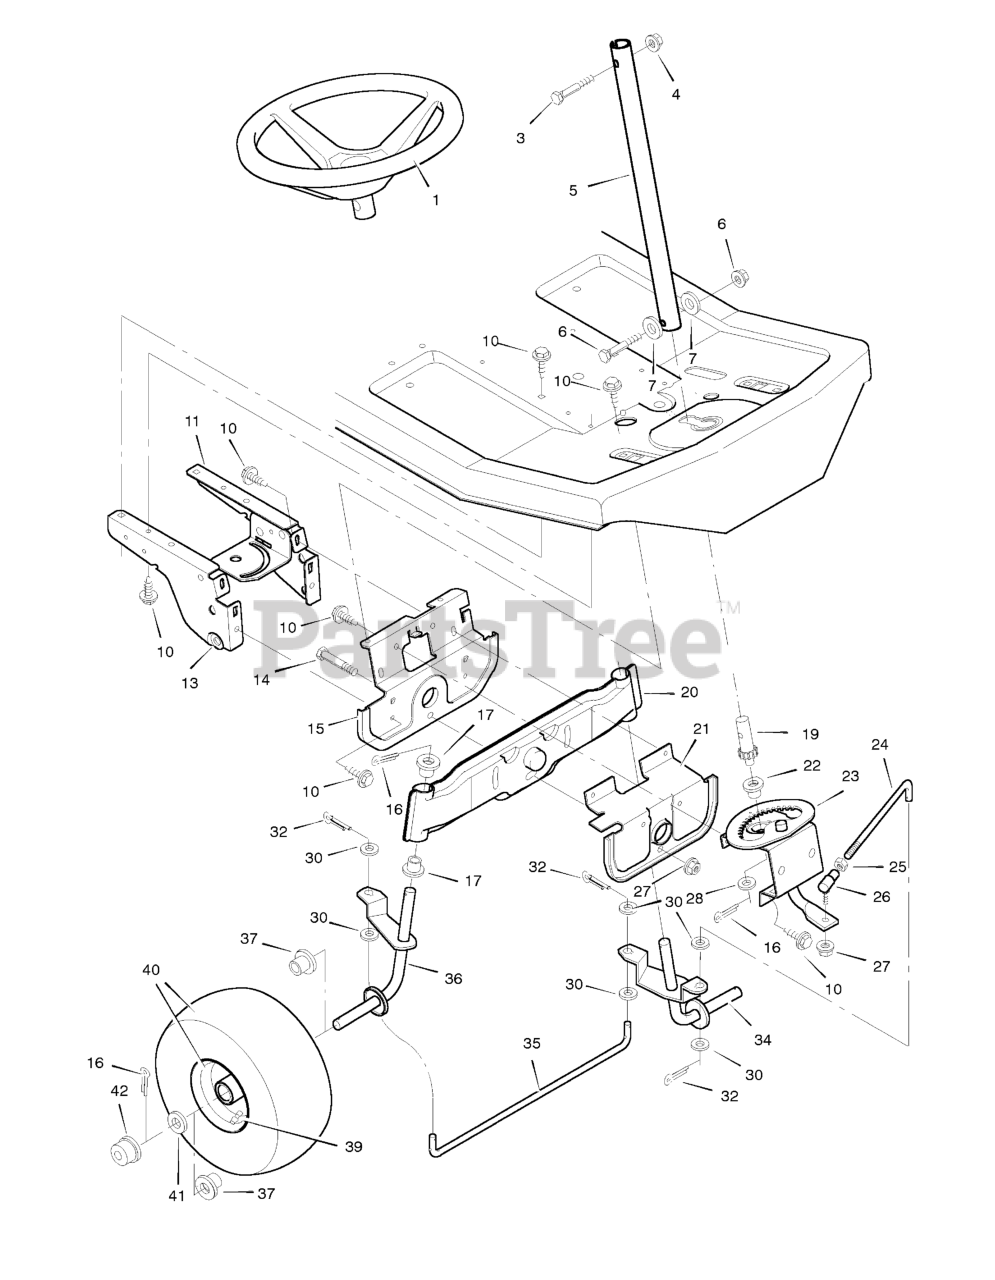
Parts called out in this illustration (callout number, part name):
1	Steering Wheel
3	Bolt, Hex
4	Locknut, Flange
5	Post, Steering
6	Nut, Hex
7	Washer
11	Plate, Left Suspension
13	Plate, Right Suspension
14	Bolt, Hex
15	Support, Front Axle
16	Pin, Cotter
17	Bearing, Spindle
19	Gear, Pinion
20	Axle Assembly, Front
21	Hanger Assembly, Front Axle
22	Bearing
23	Sector Assembly
24	Rod, Drag Link
25	Nut, Hex
26	Ball Joint, Steering
27	Locknut, Flange
32	Pin, Cotter
34	Spindle Assembly, Left
35	Rod, Tie
36	Spindle Assembly, Right
37	Bearing, Wheel
39	Valve Stem
40	Wheel & Tire Assembly
42	Cap, Hub
